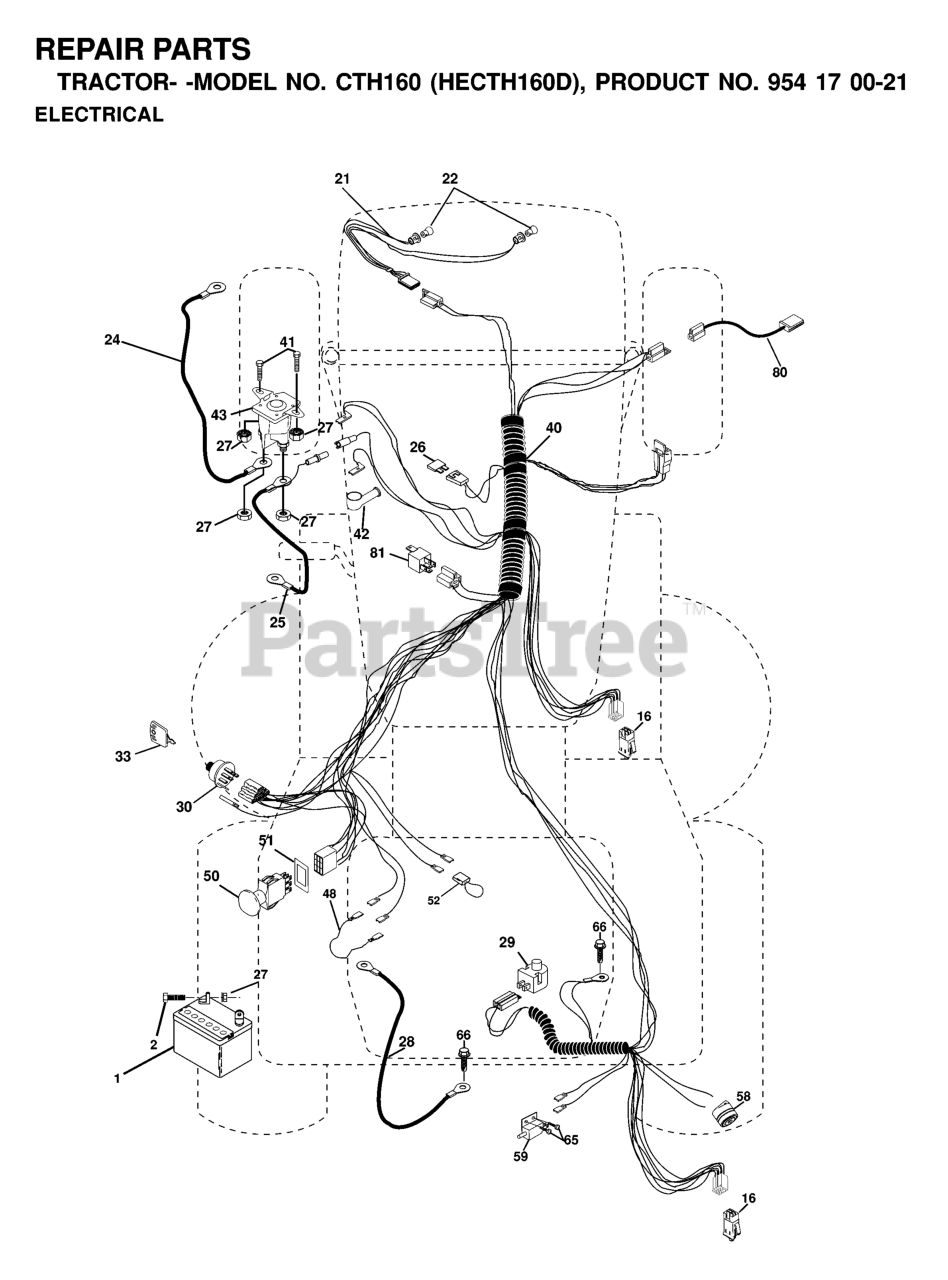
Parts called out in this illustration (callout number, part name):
1	BATTERY 12 VOLT 25 AMP
2	BOLT.HEX.1/4.X.3/4.DICHROMATE
16	SWITCH INTERLOCK
20	NUT
24	BATTERY CABLE GT
25	CABLE BATTERY
26	FUSE 15 AMP
27	NUT
28	CABLE GROUND
29	PLUNGER SWITCH (COLOR:OLIVE)
30	SWITCH IGN
33	KEY MLD GEN DELTA
40	HARNESS.ING.CRD.ELECT
41	BOLT
42	TERMINAL COVER
43	SOLINOID
48	ADAPTER.AMMETER
50	PTO SWITCH
51	FRAME RETAINING RING
52	WIRE PROTECTION LOOP
58	BUZZER
65	Screw, Hex Wsh. Tap #10-16 x 1/2
80	HARNESS, CLUTCH
81	RELAY.ASSY.T
